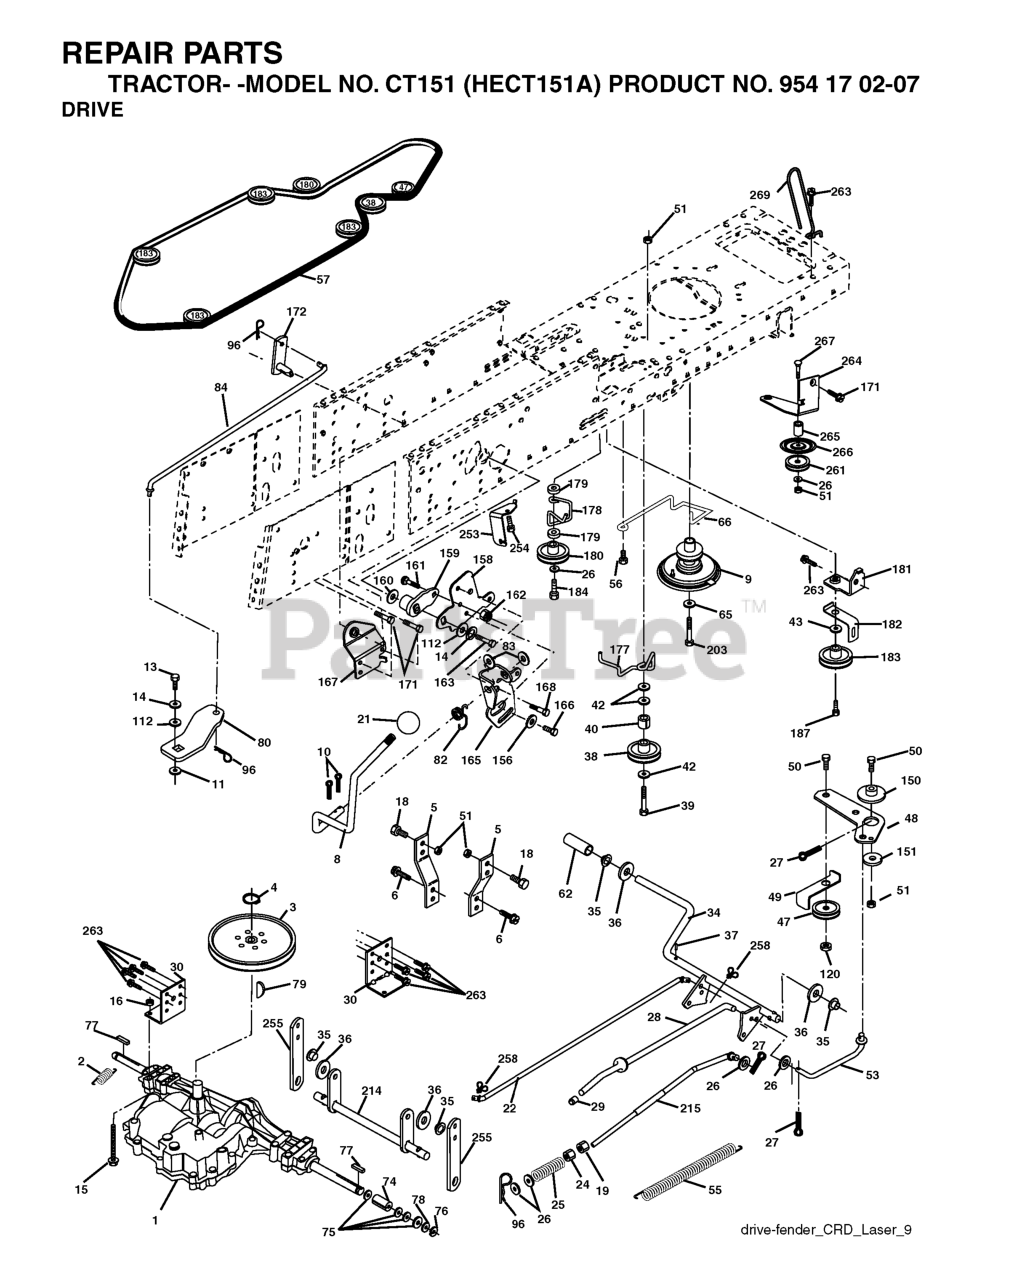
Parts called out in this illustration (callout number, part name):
2	SPRING,BRAKE RETURN
3	PULLEY
4	RETAINING RING LT
5	STRAP TORQUE
6	SCREW 5/16"
8	ROD.SHIFT.FENDER.ADJ.LT.CRD
9	RP CLUTCH.NORAM.2002
10	PIN COTTER
11	WASH-SHFT PLT LT
13	BOLT 1/4-28X3/4
14	LOCKWASHER
15	BOLT HEX 5/16-18 GR 5
16	NUT.71038.31-18.HEX.NYLOCK
19	NUT
21	KNOB.DUCKHEAD.1/2
22	ROD
24	NUT
25	SPRING ROD LT
26	WASHER
27	COTTER PIN
28	ROD, PARKING BRAKE
29	PLUNGER CAP
30	BRKT, MOUNT TRNSAXLE
34	SHAFT, FOOT PEDAL
35	BEARING.NYLON
37	DRIVE PIN
38	PULLEY.FLAT
42	WASHER
47	IDLER PULLEY
48	BELLCRANK, CLUTCH
49	RETAIN BELT
50	BOLT.3/8-16X1.50
53	LINK, CLUTCH LT
55	SPRING, RETURN LT
56	SCREW.3/8-16
57	V-BELT.KEV.111"
62	COVER, PEDAL (1 2)
65	LOCKWASHER
66	KEEPER BELT ENGINE
74	SPACER AXLE
77	SQUARE KEY
79	KEY STD (1373) DANA
82	SHIFT SPRING
83	WASHER
96	RETAINER M
120	NUT LOCK FLG 3/8-16 UNC
150	BUSHING.BELLCRANK.GRD.DR
151	WASHER 12/32X2X10GA
156	WASHER.SRRTD.5/16
158	BRACKET
159	RB HUB.SHIFT
160	Washer 29/32 x 1 - 1/4 x 16 Ga.
161	BOLT
162	NUT.CROWNLOCK.1/4
165	RP BRACKET
166	CAPSCREW.HXHD.FLG.5/16-18X.625
167	BRACKET.SUPT.SHIFT.CRD
168	BOLT.SHOULDER.5/16-18X
172	SHAFT
180	PULLEY.FLAT.IDLER
181	BRACKET
182	BELT GUIDE
184	SCREW.HXWSH.3/8
187	BOLT.5/16-18X1.25
203	BOLT.HEX.7/16-20 X 5
214	LEVER
254	SCREW 3/8-16X1
255	SHAFT
258	CLIP RETAINER
261	FLAT IDLER PULLEY
263	SCREW, 3/8-16X3/4
265	SPACER IDLER
266	PROTECTOR
269	GUARD MUFFLER
